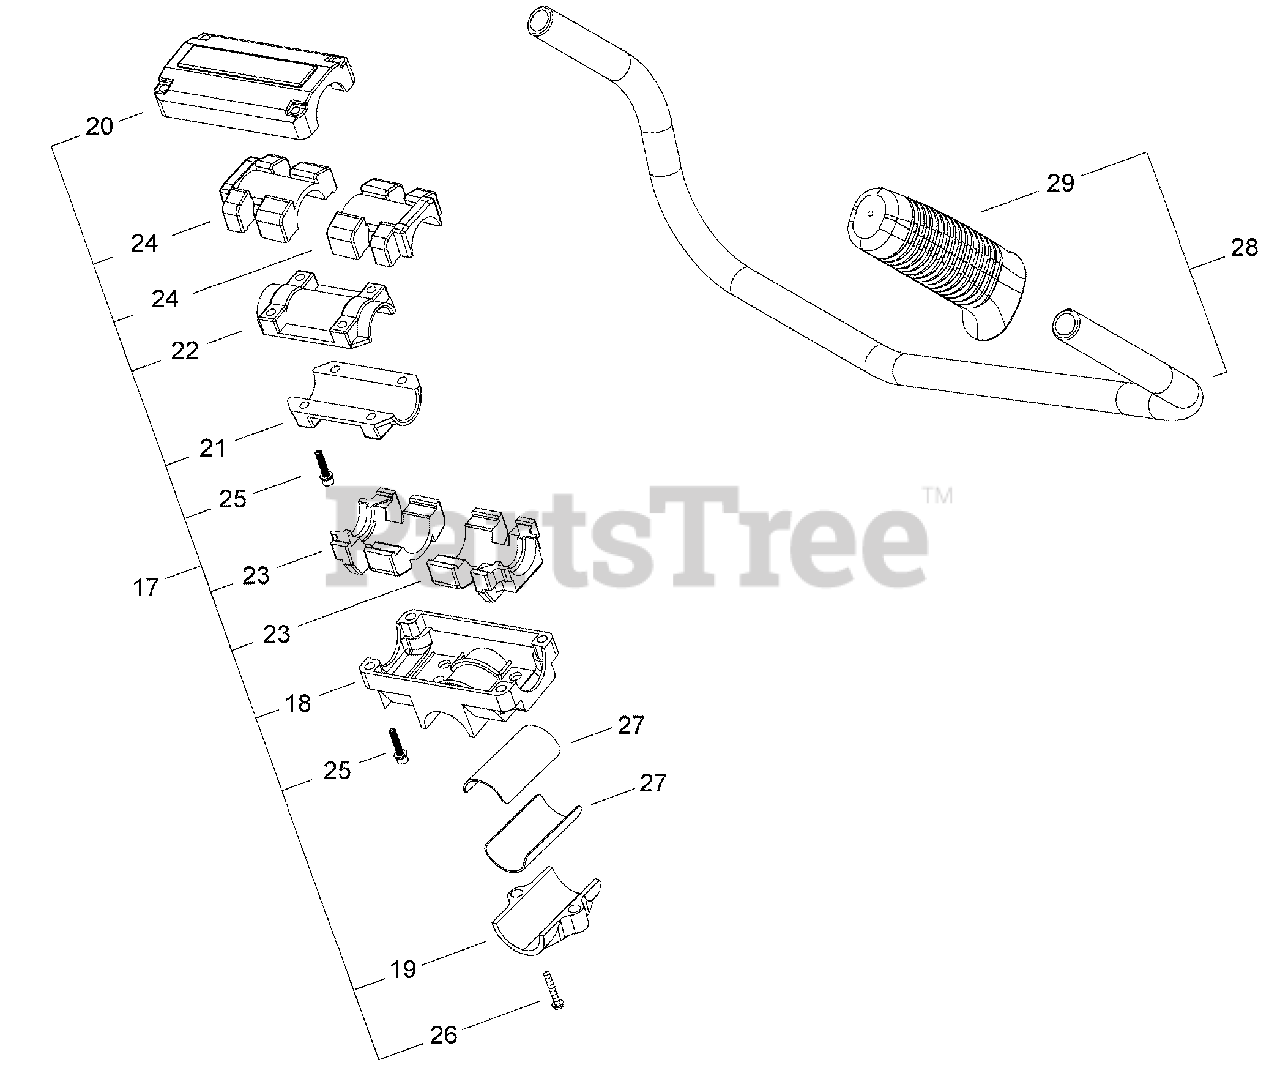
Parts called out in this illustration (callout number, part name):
17	HANDLE BRACKET KIT
18	BRACKET, HANDLE - LOWER
19	BRACKET, HANDLE - UPPER
20	BRACKET, HANDLE - UPPER
21	CLAMP - LOWER
22	CLAMP - UPPER
23	CUSHION - LOWER
24	CUSHION - UPPER
25	SCREW - 5X25
26	SCREW - 6X25
27	SPACER
28	HANDLE ASSY
29	GRIP
